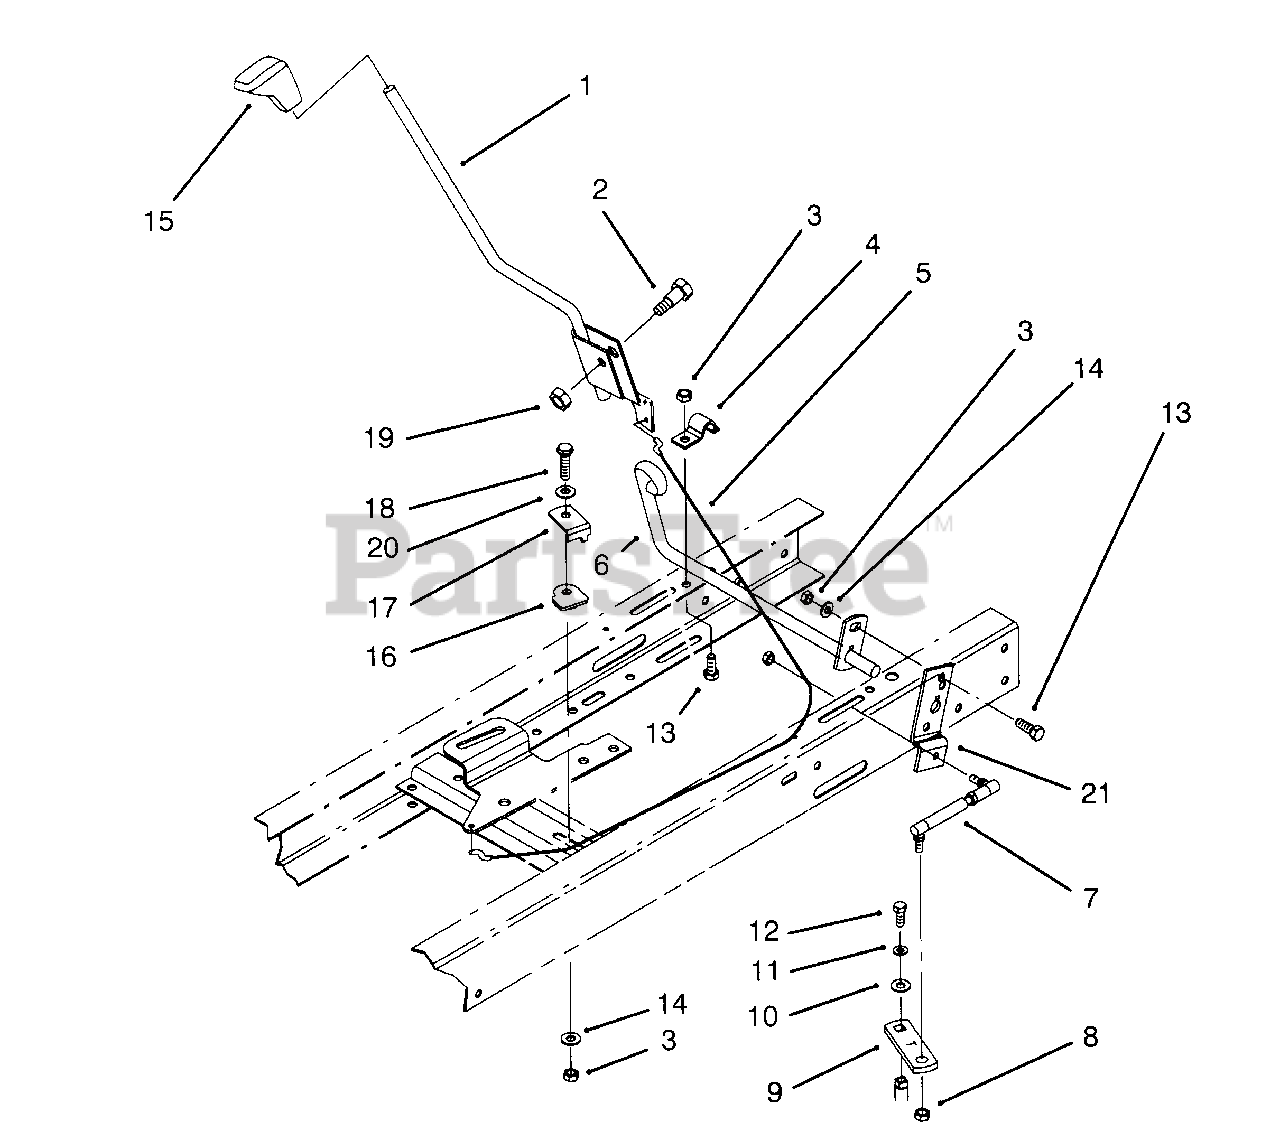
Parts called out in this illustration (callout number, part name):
1	Lever-Shift
2	Bolt-Shoulder
3	Nut-Lock
4	Clamp-Shift Pivot
5	Cable-Shotgo
6	Pivot-Shift
7	Rod-Shift Tie
8	Nut-Lock
9	Lever-Trans. Shift
10	Washer-Hardened
11	Washer-Lock
12	Screw-Hex Hd. Cap
13	Screw-Hex Hd. Cap
14	Washer-Flat
15	Knob-Shift
16	Guide-Cable
17	Keeper-Cable
18	Bolt-Carriage
19	Nut-Lock
20	Washer-Flat
21	Lever-Shift Pivot
